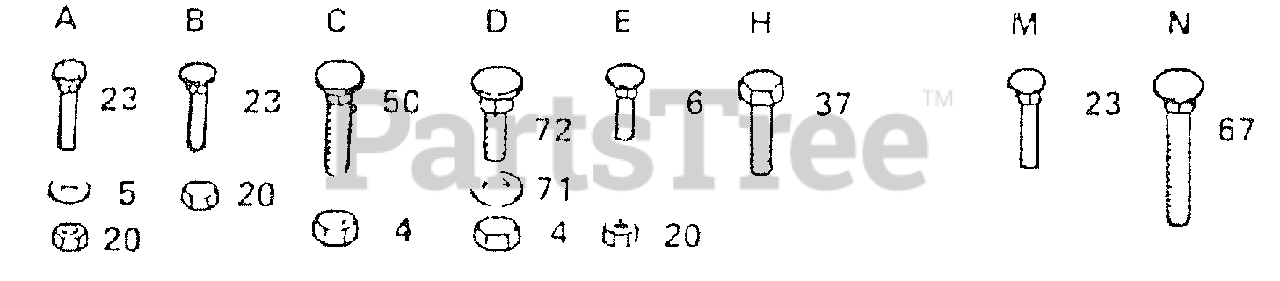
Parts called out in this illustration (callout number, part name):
4	Nut - Lock, 3/8-16
5	Washer - 11/32 x 3/4 x 16 Ga.
6	Bolt - Rd. Hd. Sq. Neck., 5/16-18 x 5/8
20	Nut - Lock 5/16-18
23	Bolt - Rd. Hd. Sq. Neckiage 5/16 18 x 3/4
37	Screw - Hex Washer Hd. 318-16 x 7/8
50	Bolt - Rd. Hd. Sq. Neckiage 3/8 16 x 3/4
67	Bolt - Rd. Hd. Sq. Neck. 3/8-16 x 1-1 /4
71	Washer - 7/16 x 1 x 10 Ga.
72	Bolt - Rd. Hd. Sq. Neckiage 3/8 16x3/4
